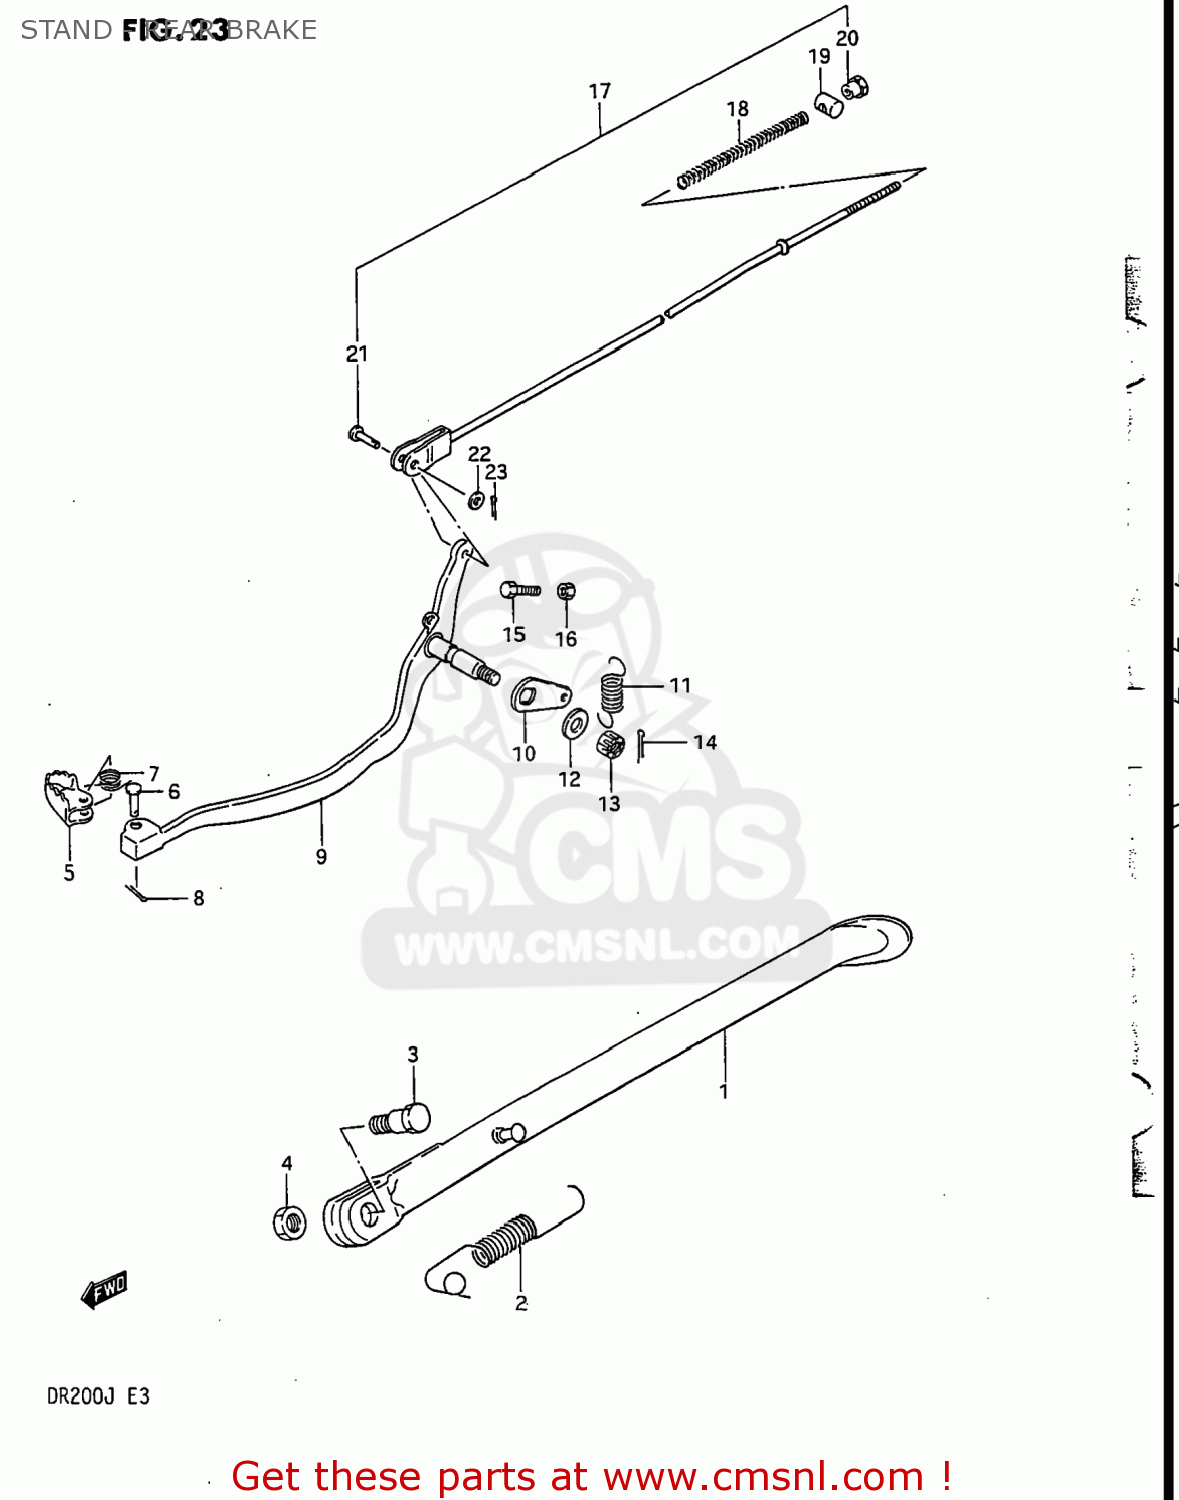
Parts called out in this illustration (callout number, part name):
1	STAND,SIDE
2	SPRING
3	BOLT L:30
4	NUT
5	PEDAL,BRAKE
6	PIN
7	SPRING
8	PIN
9	ARM,BRAKE PEDAL
10	ARM,BRAKE RETURN SPRING
11	SPRING
12	WASHER
13	NUT 8MM
14	PIN 20X20
15	BOLT(6X23)
16	NUT 6MM
17	ROD ASSEMBLY,REAR BRAKE
18	SPRING
19	PIN
20	NUT (6MM)
21	PIN(L:13.5)
22	WASHER
23	PIN 20X20
